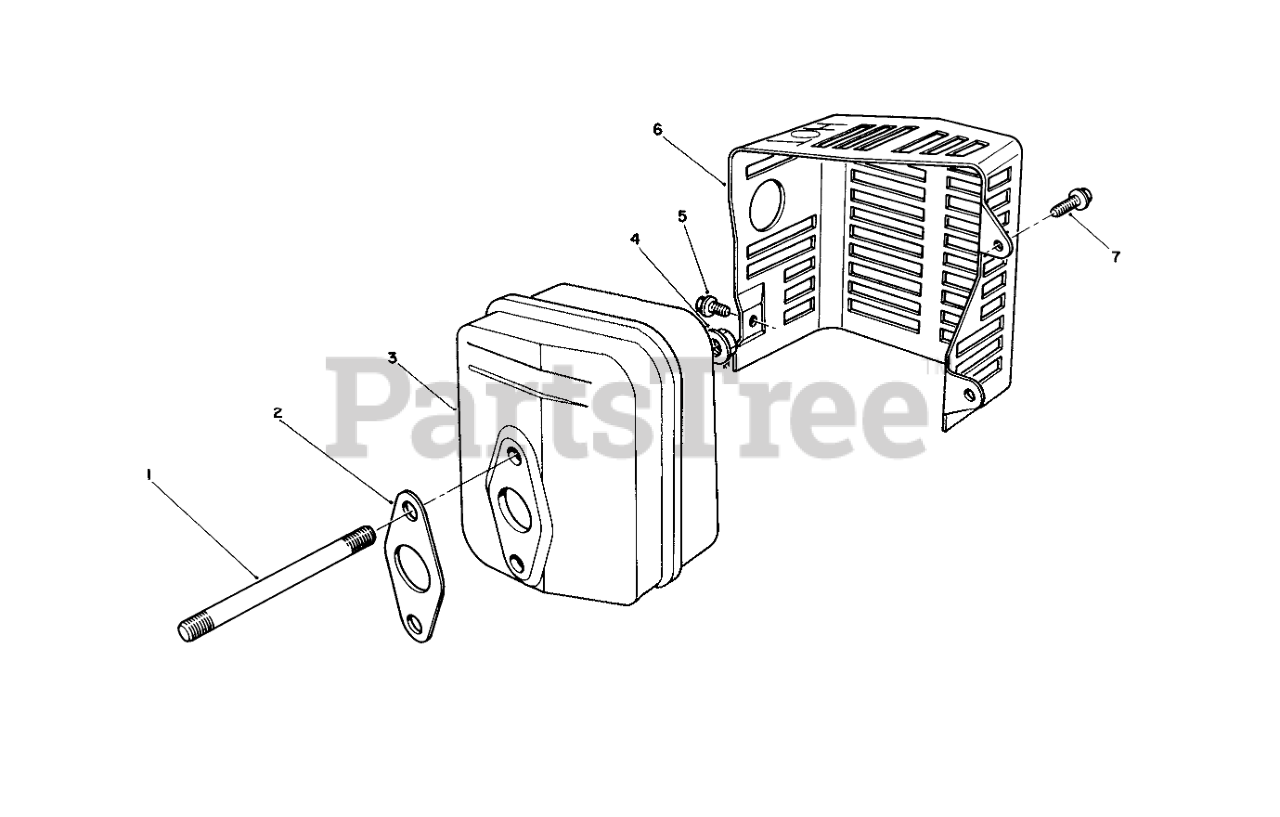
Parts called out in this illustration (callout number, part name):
2	GASKET
3	MUFFLER
5	SCREW
6	COVER
